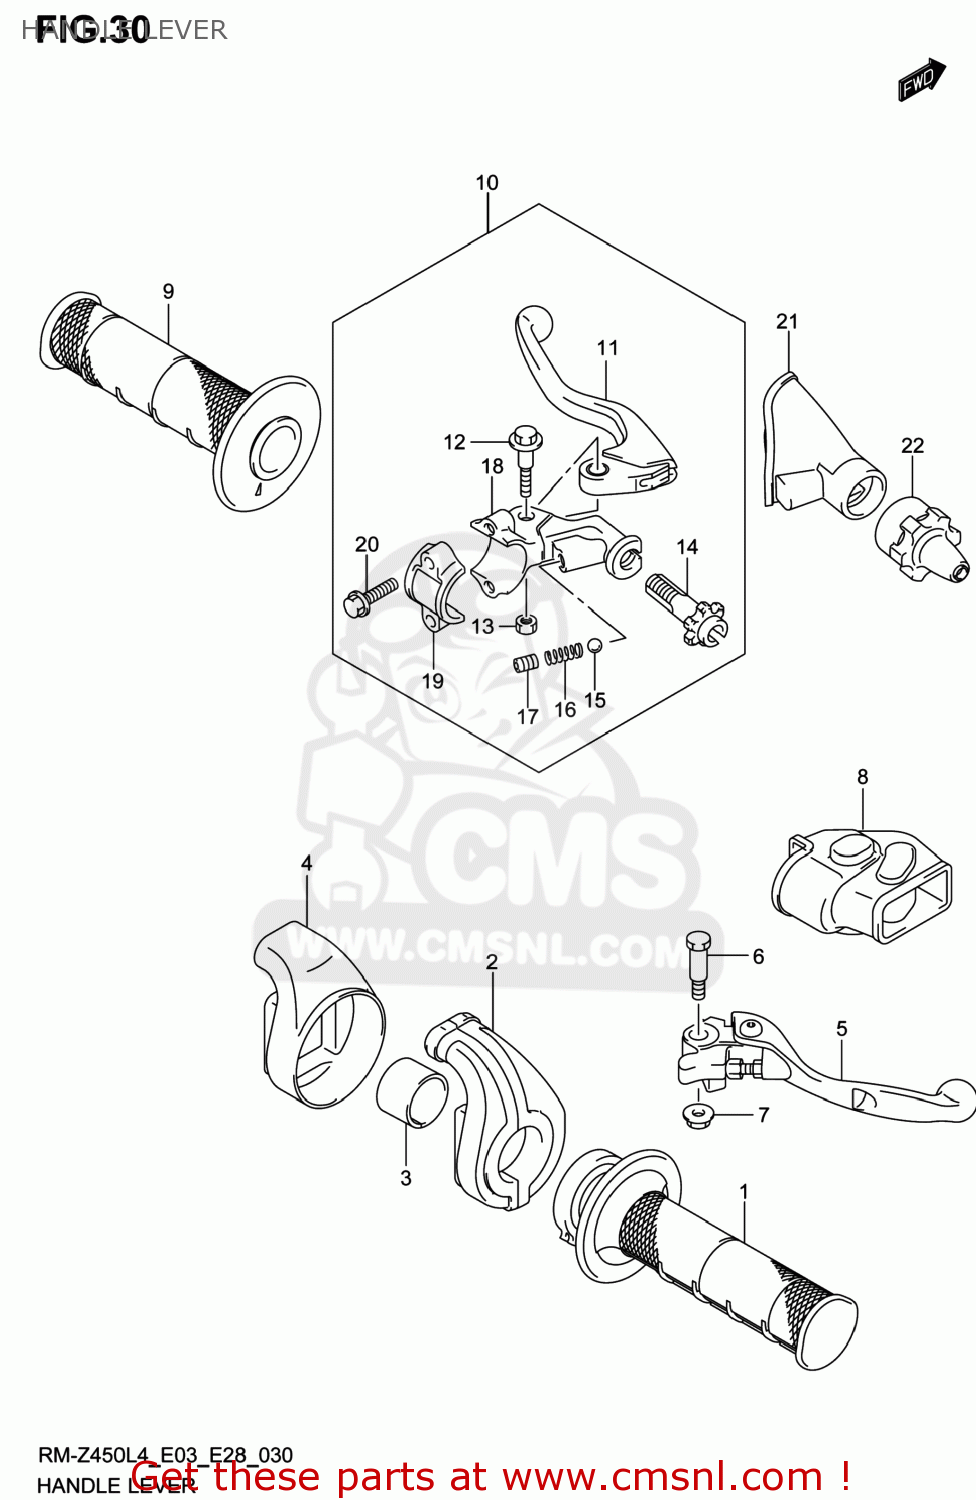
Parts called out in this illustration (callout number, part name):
1	GRIP,THROTTLE
2	CASE ASSY,THROTTLE
3	COLLAR,THROTTLE CASE
4	COVER,THROTTLE CASE
5	LEVER ASSY,BRAKE
6	BOLT,BRAKE LEVER
7	NUT
8	COVER,BRAKE LEVER
9	GRIP,L
10	LEVER ASSY,CLUTCH
11	LEVER,CLUTCH
12	BOLT
13	NUT
14	ADJUSTER,CLUTCH CABLE
15	BALL
16	SPRING
17	SCREW(6X8)
18	HOLDER,CLUTCH LEVER
19	BRACKET,CLUTCH LEVER HOLDER
20	BOLT,BRACKET
21	COVER,CLUTCH LEVER
22	COVER,CLUTCH ADJUSTER
